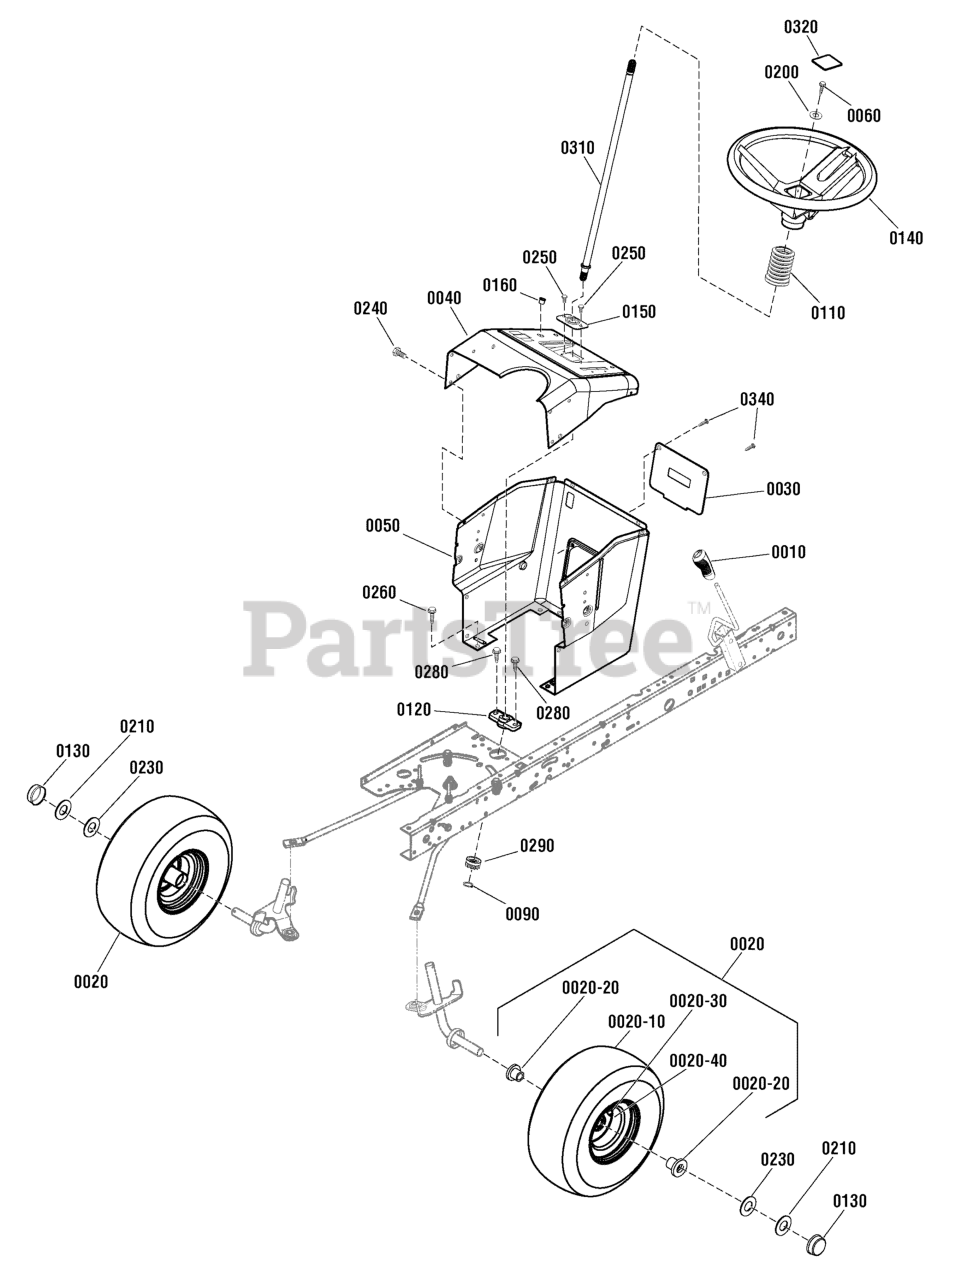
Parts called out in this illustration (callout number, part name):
1	INSERT, Steering Wheel
2	STEERING WHEEL
3	BELLOWS
4	SHAFT, Steering
5	SCREW, 5/16-18
6	BEARING, Lower
7	GEAR, Pinion
8	SNAP RING, 1/2
9	WASHER, Flat 1-3/4
10	HUB CAP
11	WHEEL & TIRE ASSY, 15X6.0-6
12	SCREW, Thread Forming, 1/4-20 x 1
13	WASHER, Flat
14	TIRE, 15 x 6 2 Ply K358
15	FITTING, Grease
16	VALVE STEM, TR412
17	WASHER, Flat, 1-1/4
19	BEARING, Steering
20	GROMMET, Parking Brake
26	SUPPORT, Dash
28	DASH, Single
29	PANEL, Access
32	SCREW, Thread Forming
37	SCREW, Hex 1/4 x 1/2
38	SCREW, Self Tap, #8 x 3/8
41	CAPSCREW, 5/16-18 x 3/4
45	BEARING, Wheel
